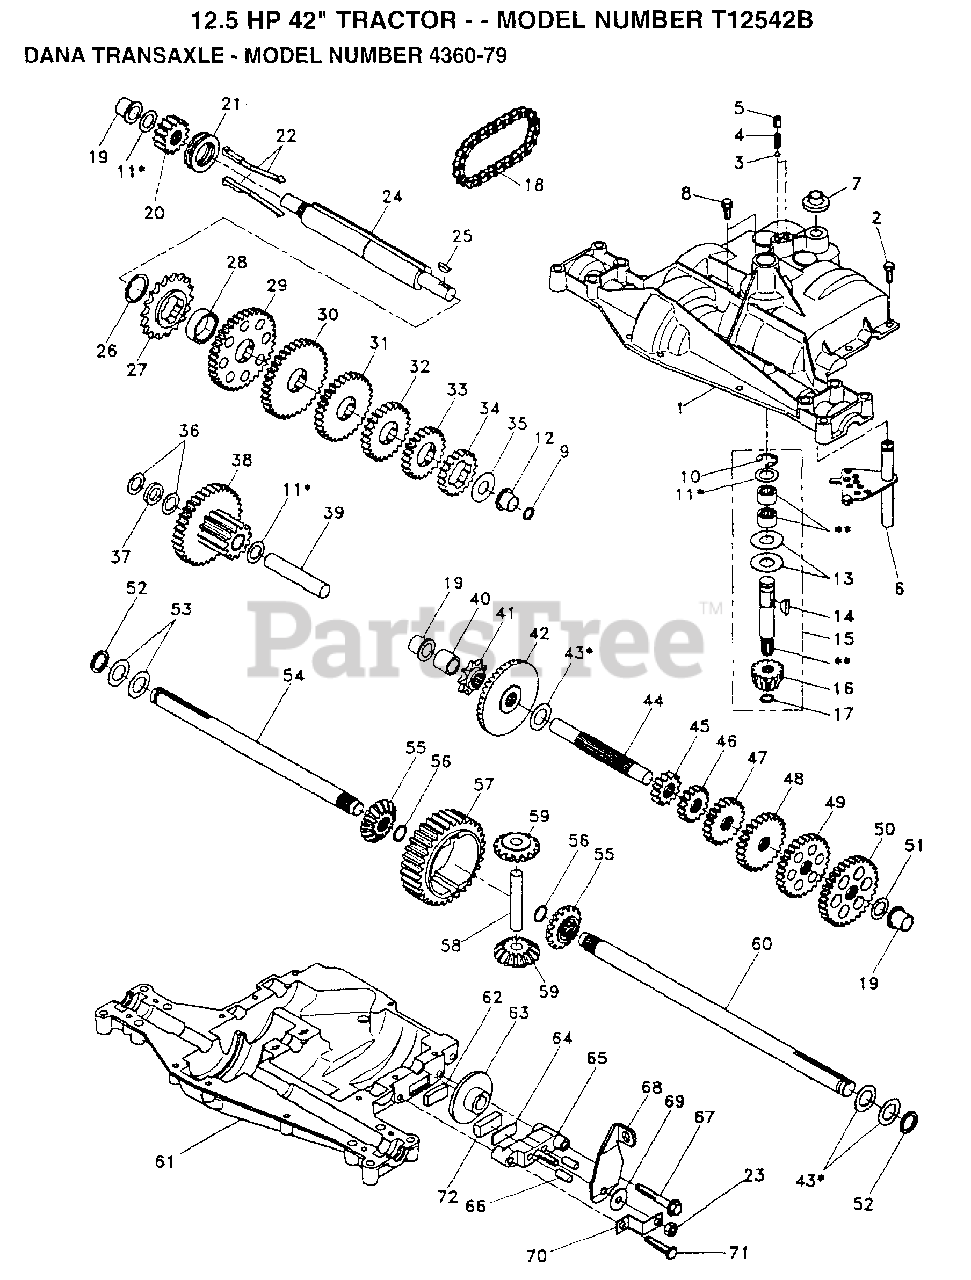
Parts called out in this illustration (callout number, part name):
1	HOUSING UPPER TRN
4	"SPRING, DETENT LT"
5	"SCREW, SET LT"
6	KIT SHIFTER ASM
7	SHIFTER BOOT
8	SCREW TAP W/SEAL
9	SQUARE RING
11	ASM KIT SHIM 4689
12	BEARING FLAN-DANA
13	WASHER T
14	KEY WOODRUFF-DANA
15	AS KIT INPUT SHFT
16	PINION 14T T
17	"RING,RETAINING LT"
18	"CHAIN,24 PTCH LT"
19	BEARING.FLNG.5510
20	GEAR SPUR 14 TTH
21	COLLAR CLUTCH
22	ASM KIT CLTCH KEY
23	NUT.LOCK.5/16-24
24	SHAFT INTERM DANA
25	WOODRUFF KEY
26	"RING,RETAINING LT"
27	SPROCKET 18T T
28	SPACER YT
29	GEAR SPUR 37 TTH
30	GEAR SPUR 35 TTH
32	GEAR 25T LT
33	GEAR SPUR 22 TT
34	SPUR GEAR 19T
35	"WASHER, PLAIN LT"
36	WASHER 025
37	SPACER
38	ASSM GEAR COMB
39	SHAFT IDLER
40	SPACER T
41	SPROCKET 9T LT
43	ASM KIT SHIM
44	SHAFT T
45	GEAR SPUR 12 TTH
46	GEAR SPUR 15 TTH
48	"GEAR, SPUR 25T LT"
49	GEAR 28T T
50	"GEAR, SPUR 31T LT"
51	WASHER 060
52	NEOPRENE WASHER
53	WASHER 031
55	GEAR 15T T
56	"RING,RETAINING LT"
58	SHAFT T
59	GEAR 1ST T
61	HOUSING LOWER TNS
62	PUCK T
63	BRAKE DISC. T
64	SPACER LT
66	PIN T
69	WASHER LT
71	"SCREW, TAPPING LT"
72	PUCK T
